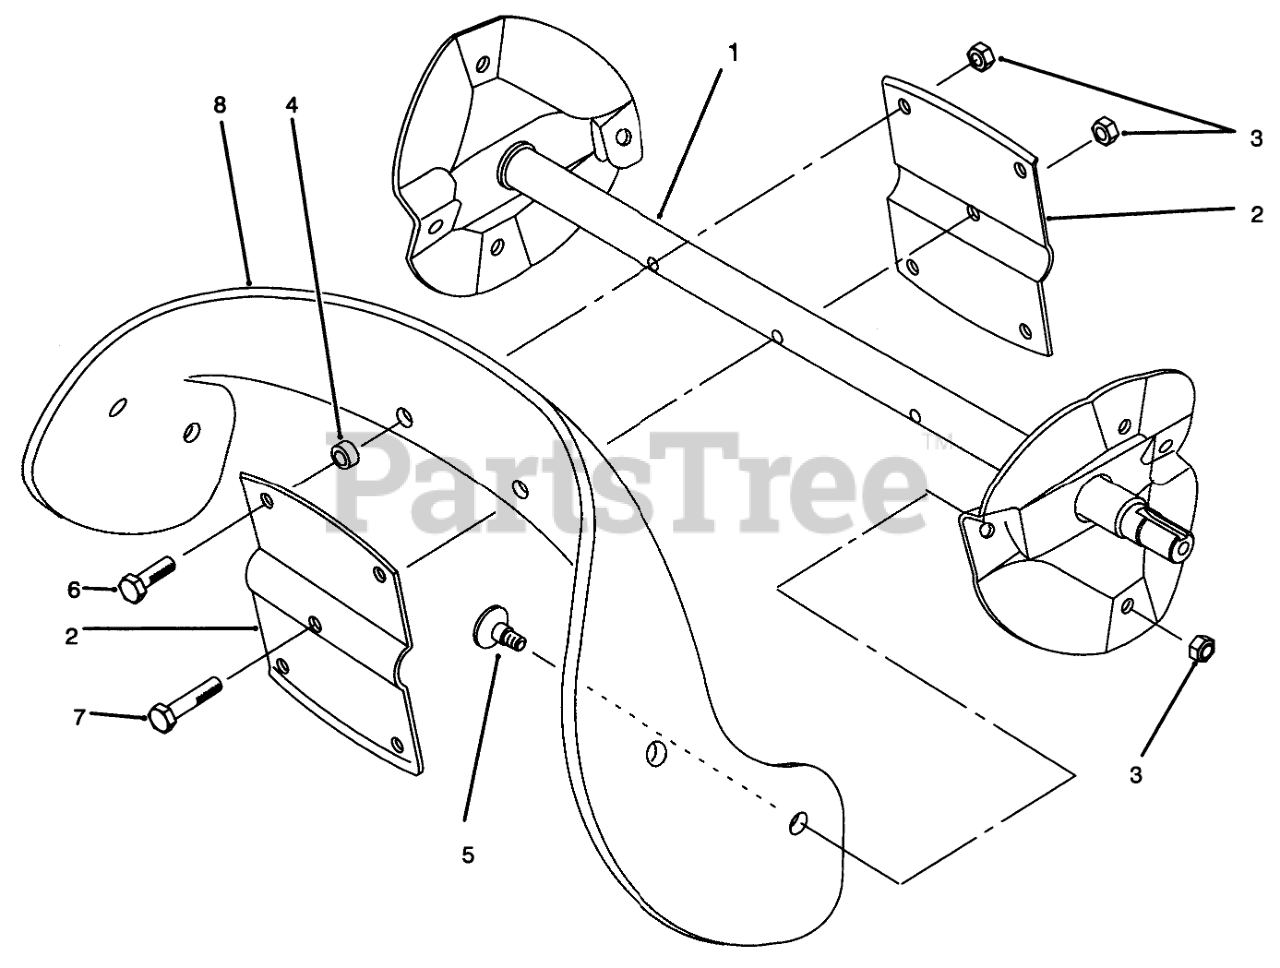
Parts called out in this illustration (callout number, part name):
1	Wa-Rotor
2	Rotor
3	NUT-LOCK, NI
4	SPACER-BLADE, ROTOR
5	SCREW
6	SCREW-HH
7	SCREW-HH
8	Blade-Rotor
